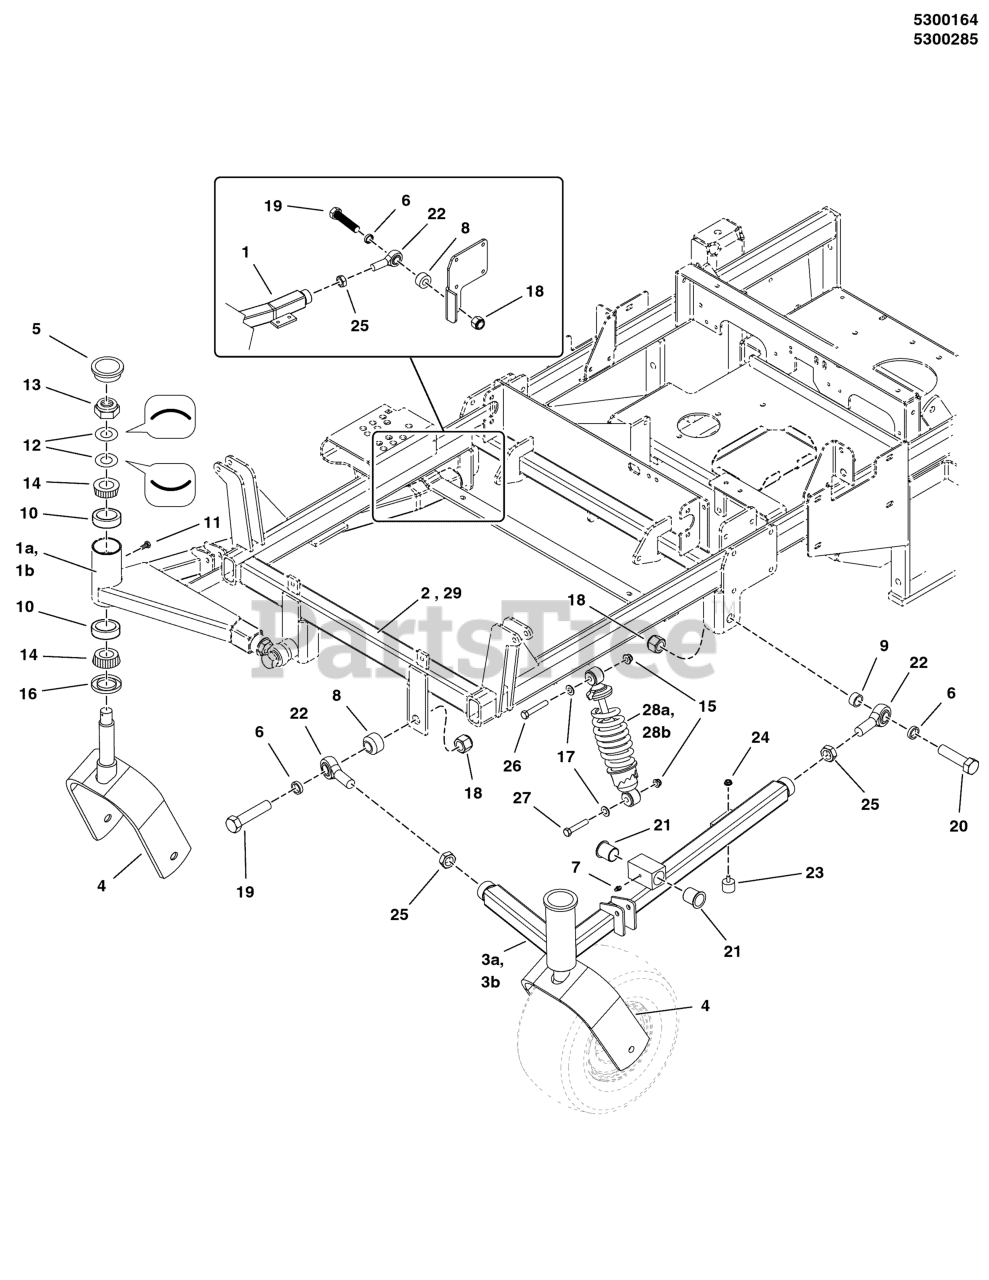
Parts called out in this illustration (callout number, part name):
2	WELD, MAIN FRAME, IS3100Z - RED
4	WELD, CASTER YOKE -RED
5	CAP, GREASE, LOW PROFILE
6	SPACER, .76 X 1.00 X .25
7	GREASE FITTING, 1/4-28 STRAIGHT
8	SPACER, .75 X 1.50 X 1.00, CZ
9	SPACER, .76 X 1.00 X .50, CZ
10	BEARING CUP
11	BOLT, 1/4-28 X 1/2, GD5 YZ
12	WASHER, BELLEVILLE - 1.500 X .755
13	NUT, 3/4-16, HEX JAM NYLON LOCK
14	BEARING, TAPERED ROLLER, 1
15	NUT, 3/8-16 HEX NYLOCK FLANGE
16	SEAL, GREASE
17	WASHER, 3/8 GD.9 FLAT
18	NUT, 3/4-16 HEX NYLON LOCK
19	BOLT, 3/4-16 X 3-1/2 YZ GD5
20	BOLT-3/4-16 X 3 YZ GD5
21	BUSHING, 1.00 X 1.13 X 1.38, PLASTIC
22	BALL JOINT, 3/4-16, MALE
23	BUMPER, RUBBER 1/4-20
24	NUT, 1/4-20 HEX SERR. FLANGE
25	NUT, 3/4-16 HEX JAM
26	BOLT, 3/8-16 X 2-1/4" GD5 CZ
27	BOLT, 3/8-16 X 2, GD5, CZ
29	WELD, MAIN FRAME, IS3100Z - RED
